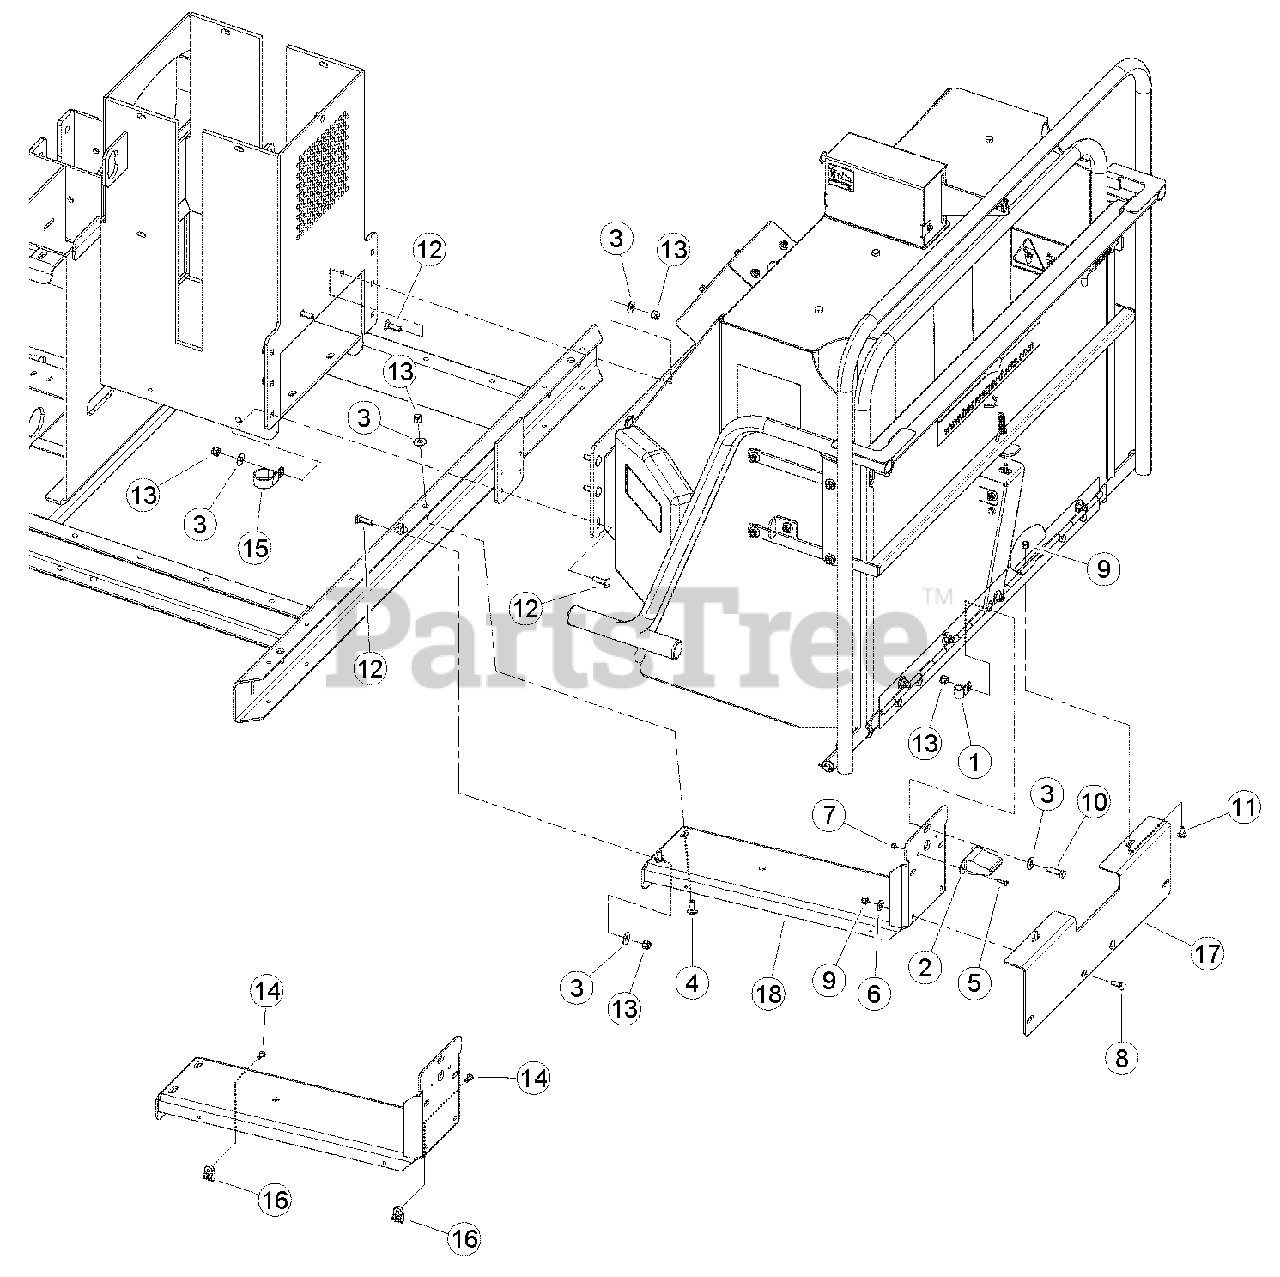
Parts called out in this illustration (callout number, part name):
1	ADAPTER, -10 MORING / -8 MJIC 90 DEG.
2	ADAPTER, -8 MORING / -8 MJIC
3	ADAPTER, -10 MORING / -8 MJIC
4	ADAPTER, -8 MORING / -8 MJIC 90 DEG.
5	MOTOR, 45 CU. IN. HYDRAULIC
6	FILTER, SPIN-ON
7	ADAPTER, -10 MORING / -10 MJIC 90 DEG.
8	ASSEMBLY, SA - 1987 VALVE
9	HOSE ASSEMBLY, -10 FMJIC / -10 FMJIC LD 90 X 21"
10	HOSE ASSEMBLY, -8 FMJIC / -8 FMJIC 90 X 21"
11	HOSE ASSEMBLY, -8 FMJIC / -8 FMJIC 90 X 61"
12	HOSE ASSEMBLY, -8 FMJIC / -8 FMJIC X 61"
13	HOSE, .75 ID. X 24" 100R4 HYD.
14	CLAMP, 1" OD. HOSE T-BOLT
15	PUMP, PB CW HI/LO .646 DISP.
16	ADAPTER, -10 MORING / .75 90 BEAD HOSE
17	ADAPTER, -8 MORING / -8 MJIC 90 DEG.
18	WELDMENT, HYDRAULIC TANK
